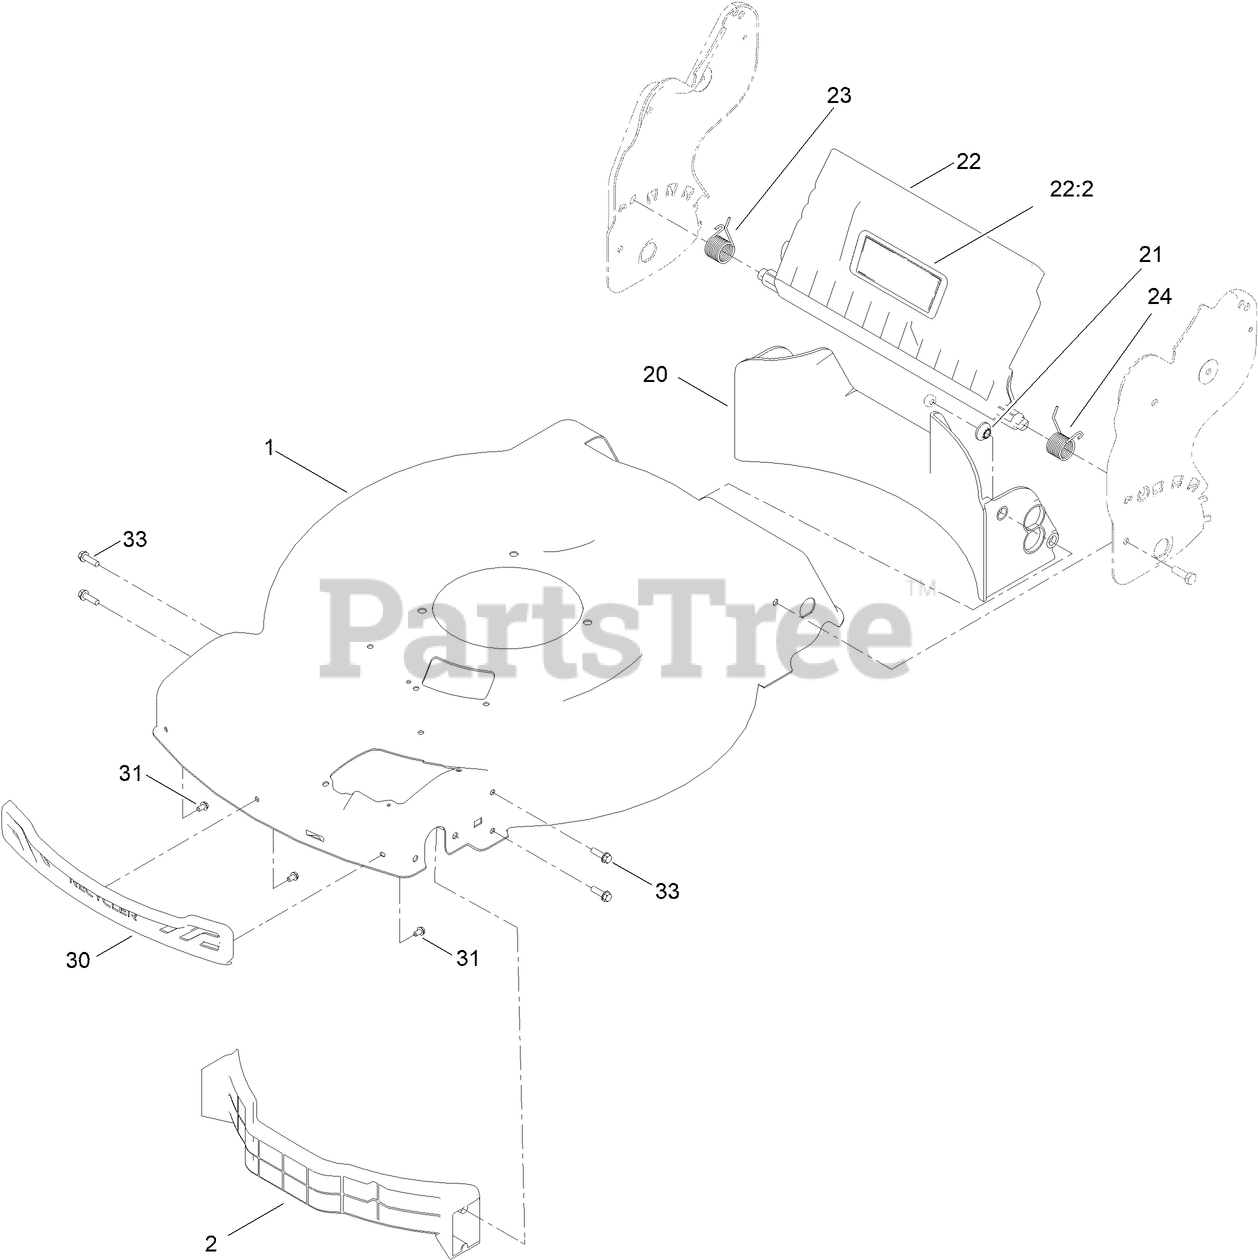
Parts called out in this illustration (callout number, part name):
1	HOUSING ASM
2	BAFFLE-FRONT, DOMESTIC
20	BAFFLE-REAR, FWD
21	WASHER-STEPPED, BAFFLE
22	REAR DEFLECTOR ASM
22:2	DECAL-WARNING
23	SPRING-TORSION
24	SPRING-TORSION
30	BUMPER-FRONT
31	SCREW-PLASTIC, HWH
33	SCREW-HWH
